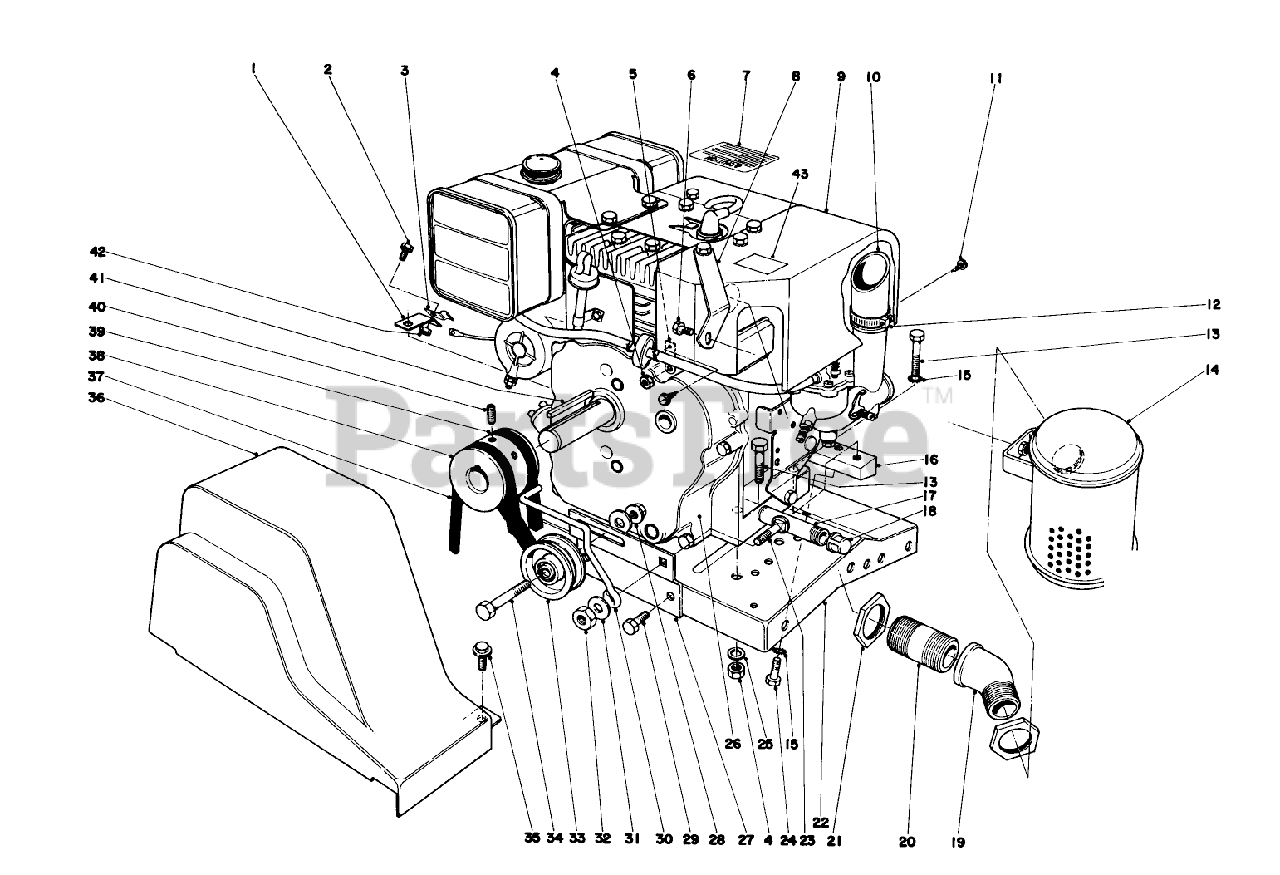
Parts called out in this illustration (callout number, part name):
1	Bracken Wire Clamp
2	SCREW-HWH
3	CABLE CLAMP
4	NUT-LOCK, CONE
5	Standoff-Heater Box
6	5/16-18 X 5/8 SEMS SC
7	Decal Instruction
8	Bracket Muffler Mounting
9	Heater Box
10	Carburetor Stack
11	SCREW-HWHTF
13	SCREW-HH
14	Muffler
15	WASHER-LOCK
16	Block Engine Mounting
17	NIPPLE-PIPE
18	CAP-PIPE
19	Elbow
20	Exhaust Pipe
21	Locknut
22	Base-Engine
23	SCREW-CARR
24	SCREW-HH
25	Washer
26	Engine
27	Belt Idler Bracket
28	NUT-HHF, WHIZ
29	SCREW-HHFTF
30	BELT GUIDE
31	WASHER-FLAT
32	NUT-HEX
33	PULLEY B
34	SCREW-HH
35	SCREW-HWH
36	Belt Guard
37	V-Belt
38	Pulley
39	V-BELT
40	Screw-Set
42	NUT-KEPS
43	Decal-Tecumseh
